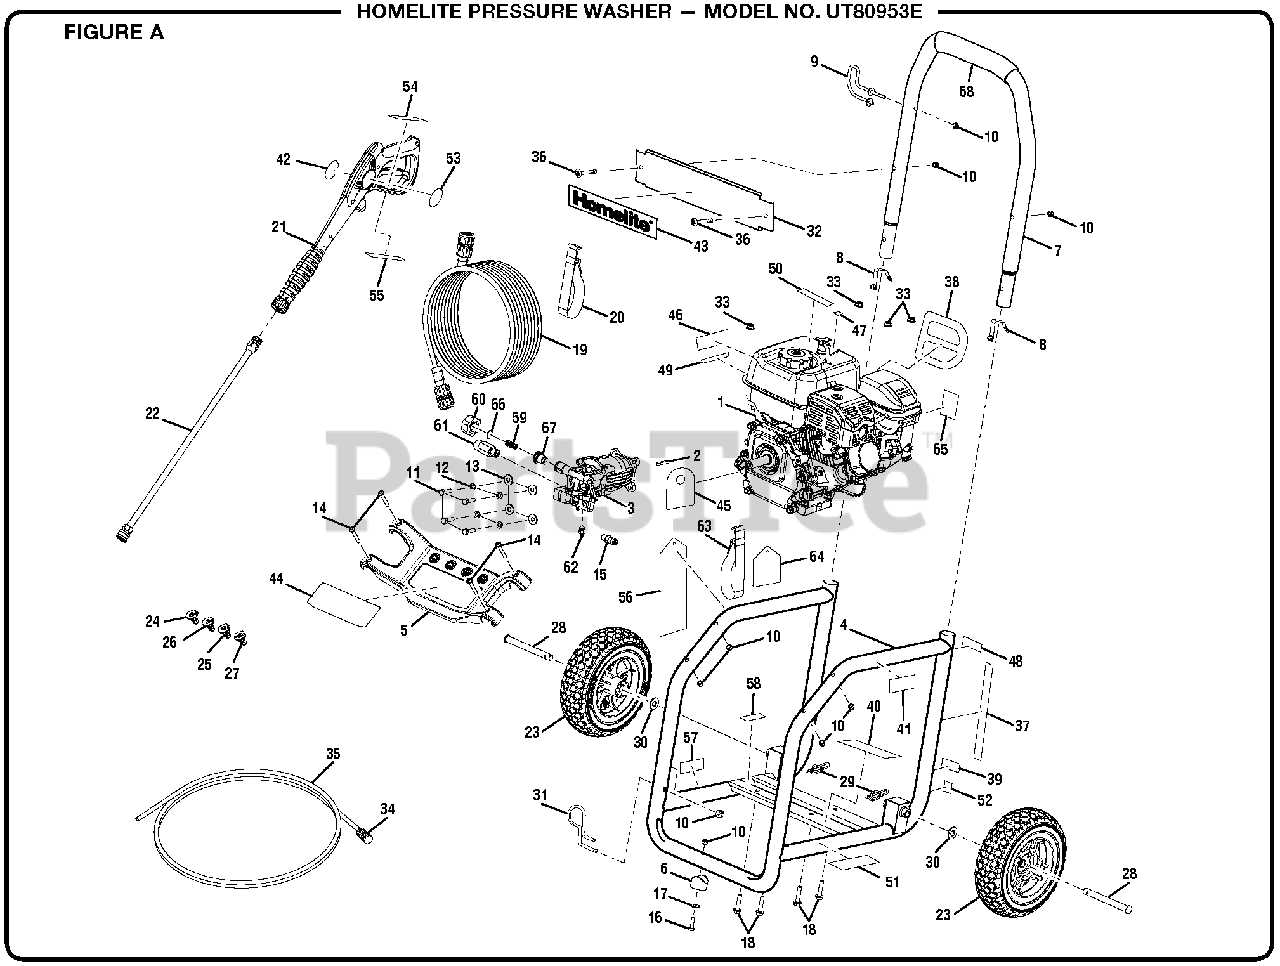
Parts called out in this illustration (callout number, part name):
1	Engine (RATO 180cc)
2	Output Shaft Key (3/16 x 40 mm)
4	Main Frame
5	Nozzle Holder
6	Rubber Foot
7	Handle Assembly
8	Lock Button w/Spring Clip
9	Wand Holder (Upper)
10	Lock Nut (1/4-20)
11	Bolt (5/16-24 x 27 mm, Hex Hd.)
12	Lock Washer (5/16 in.)
13	Washer (5/16 in.)
14	Screw (1/4-20 x 2.0 in., Torx)
15	Thermal Release Valve
16	Bolt (1/4-20 x 1-1/4 in.)
17	Washer (1/4 in.)
18	Bolt (M8 x 40 mm, Hex Flange Hd.)
20	Hook and Loop Strap
21	Trigger Handle
22	Spray Wand Assembly
23	Wheel Assembly 10 in. x 3 in.)
24	Nozzle, 0º
25	Nozzle 40º
26	Nozzle 25º
27	Soap Nozzle
29	Hitch Pin
30	Washer (1/2 in.)
31	Wand Holder (Lower)
32	Front Panel
33	Lock Nut (M8 x 1.25)
35	Chemical Siphon Tube
36	Screw (1/4-20 x 1.57 in., Torx T-30)
37	Quick Start Label
38	Recoil Label
39	Choke Label
40	Data Label
41	Hot Surface Label
42	Trigger Handle Logo Label
43	Homelite Label
44	Performance Label
45	Add Oil Label
46	Danger Label
47	E85 Label
48	Homelite Inquiries Label
49	EMC Compliance Label
50	No Oil to Gas Label
51	Combustion Label
52	Fuel Label
53	Warning Label
54	Warning Label (French and Spanish)
55	Wand Label (Max Rating)
56	Danger Hangtag
57	Lubricant Label
58	Dip Stick Label
60	Inlet Adapter
61	Outlet Tube
62	Soap Injector Kit
63	Hook and Loop Strap
64	Nozzle Instructions Hangtag
65	Engine Label (On-Off)
67	Inlet Connector
68	Foam Grip
